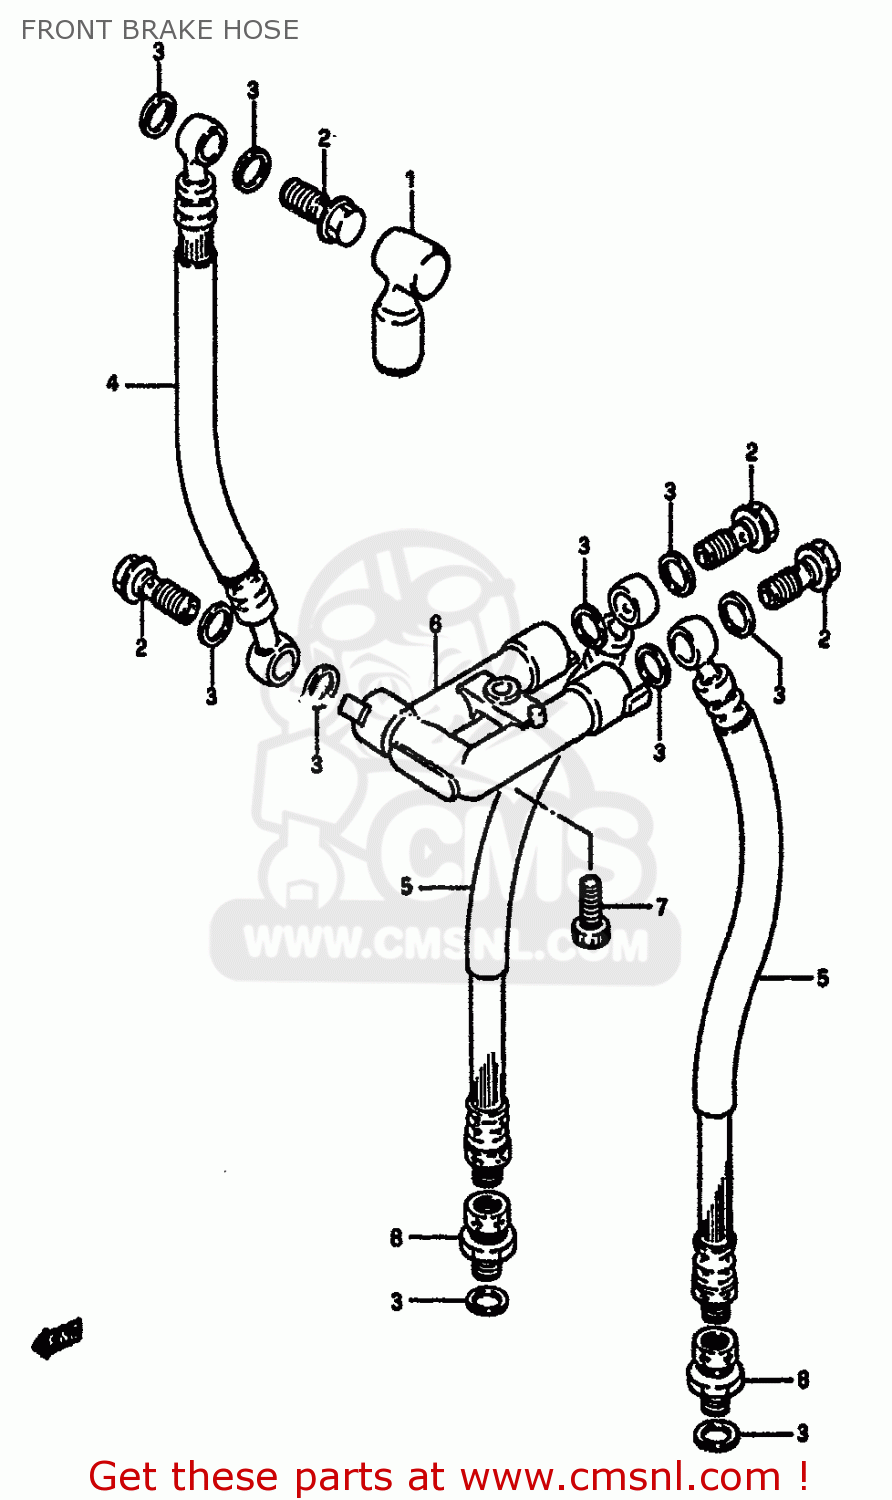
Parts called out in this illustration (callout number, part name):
1	BOOT,MASTER CYLINDER
2	BOLT UNION
3	WASHER(10X15X1.5)
4	HOSE,FRONT BRAKE
5	HOSE,FR BRAKE NO.2
6	JOINT,BRAKE HOSE
7	BOLT
8	ADAPTER,BRAKE HOSE
